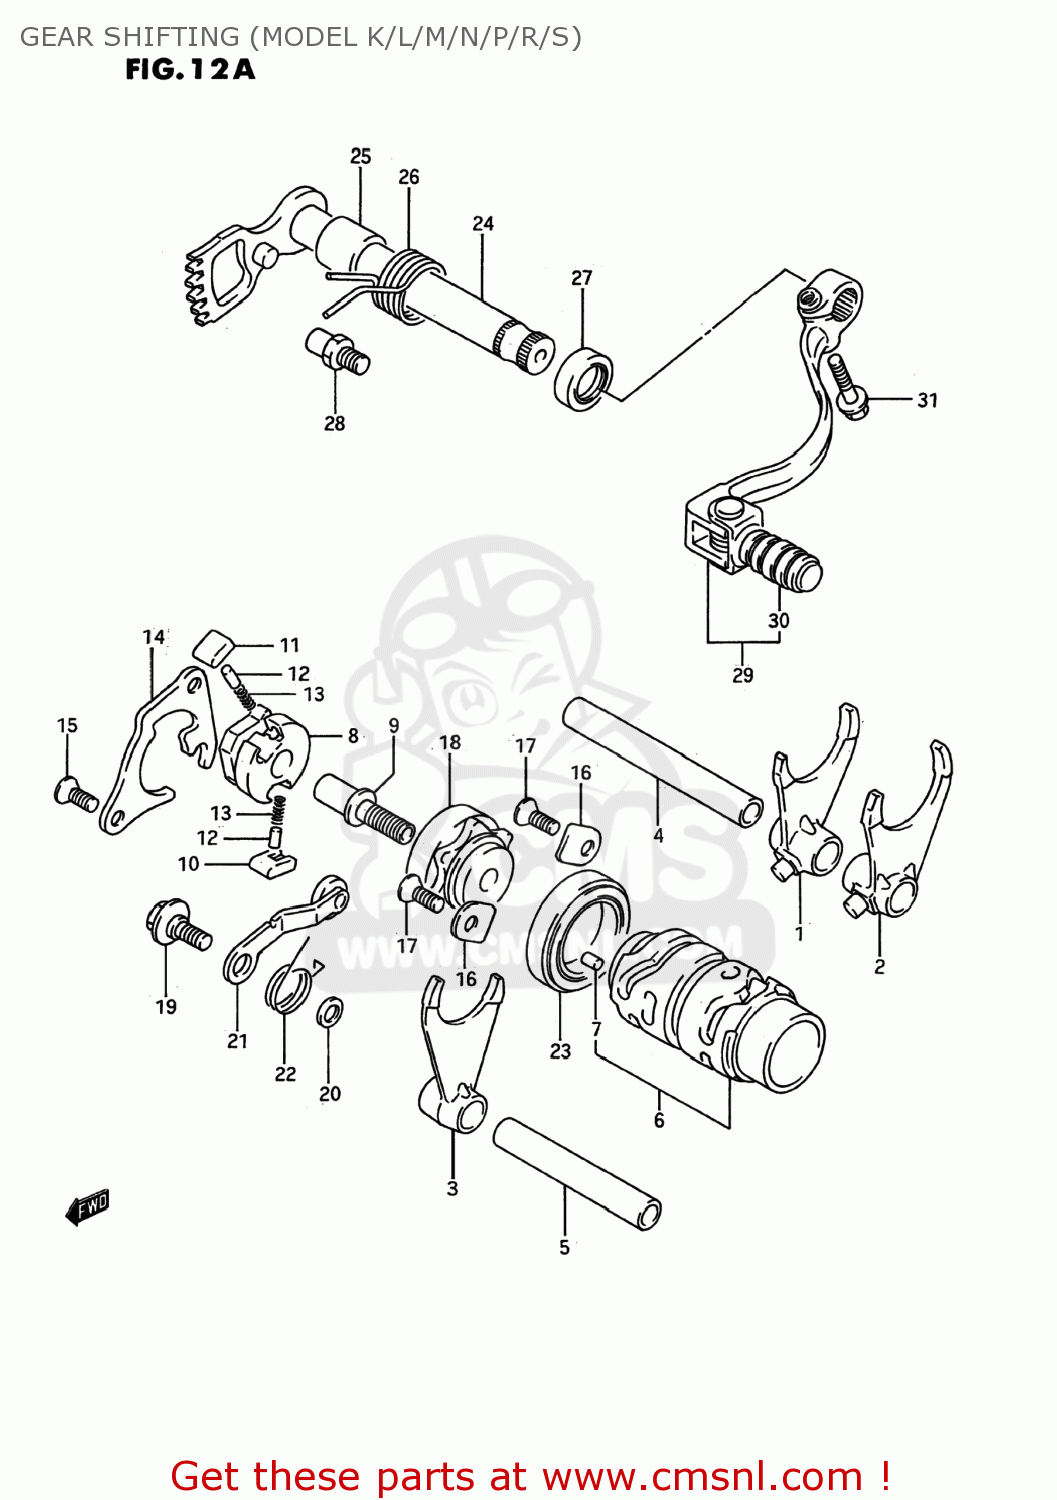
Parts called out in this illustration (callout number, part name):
1	FORK,GEAR SHIFT NO.1
2	FORK,GEAR SHIFT NO.2
3	FORK,GEAR SHIFT NO.3
4	SHAFT,GEAR SHIFT FORK
5	SHAFT,GEAR SHIFT FORK
6	CAM,GEAR SHIFT
7	PIN
8	GEAR,GEARSHIFT CAM DRIVE
9	PIN,SHIFT CAM DRIVEN GEAR
10	PAWL,GEAR SHIFT NO.1
11	PAWL,GEAR SHIFT NO.2
12	PIN(5X8)
13	SPRING
14	LIFTER,GEAR SHIFT POLE
15	SCREW
16	RETAINER,COUNTER BEARING,R
17	SCREW
18	PLATE,GEAR SHIFT CAM STOPPER
19	BOLT(6X14.3)
20	WASHER
21	STOPPER,SHIFT CAM
22	SPRING
23	BEARING
24	SHAFT,GEAR SHIFT
25	SPACER(14X20X17.5)
26	SPRING
27	SEAL,OIL(14X22X7.3)
28	STOPPER,GEAR SHIFT CAM
29	LEVER ASSEMBLY,GEAR SHIFTING
30	RUBBER,GEAR SHIFT PEDAL
31	BOLT,G/S SWITC
